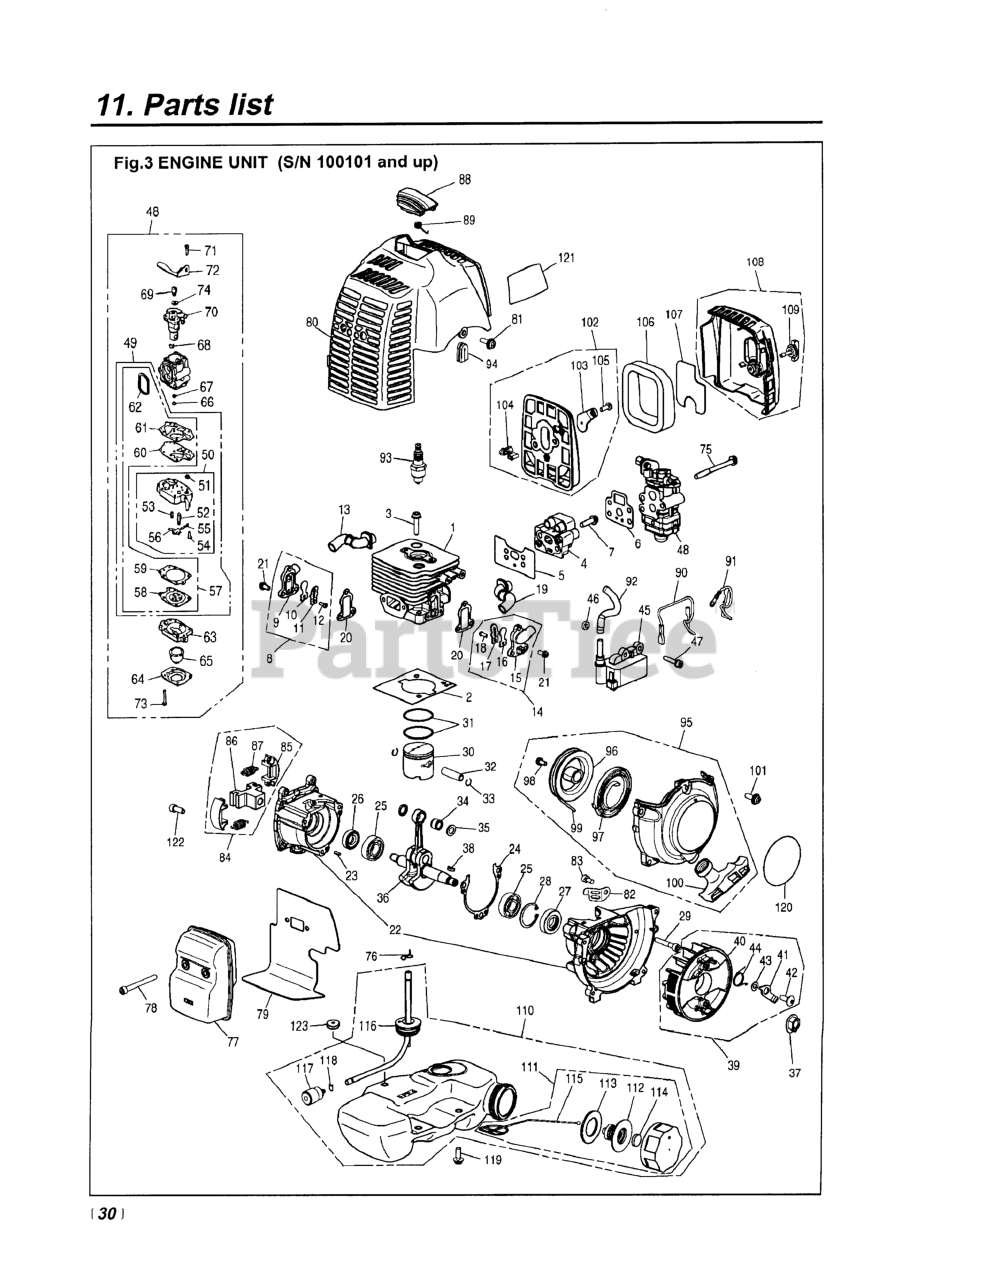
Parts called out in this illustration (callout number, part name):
1	CYLINDER (RPLS -12110)
2	GASKET, BASE
3	BOLT
4	INSULATOR (RPLS. -13160/13161)
5	GASKET INSULATOR
6	GASKET, CARBURETOR
7	BOLT (RPLS 2850-14220)
9	CASE VALVE
10	VALVE, REED
11	STOPPER
12	SCREW, M3 x 8
13	PIPE, AIR
16	VALVE, REED
17	STOPPER
18	SCREW, M3 x 8
19	PIPE, AIR (F)
20	GASKET, VALVE
21	BOLT, TORX
22	CRANKCASE COMPLETE
23	PIN
24	GASKET
25	BEARING
26	SEAL
27	SEAL, OIL (RPLS 1140-21220)
28	RING, SNAP, M28 x 1.2
29	BOLT
30	PISTON
31	RING, PISTON
32	PIN, PISTON
33	RING, SNAP (RPLS 1101-41320)
34	BEARING (RPLS 1140-41330)
35	WASHER
36	CRANKSHAFT-C
38	KEY
39	ROTOR ASSEMBLY
41	PAWL
42	SCREW
43	WASHER
44	SPRING
45	COIL ASSEMBLY
46	SPACER (RPLS -71260)
47	BOLT TORX
48	T1501-81001 (WYA-4-1)
49	KIT, REBUILD (RPLS -06030)
50	PUMP BODY ASSEMBLY
51	SCREEN
52	VALVE, INLET
54	SCREW
55	PIN
56	LEVER
57	KIT, GASKET (REPLACES-06020)
58	DIAPHRAGM
59	GASKET, DIAPHRAGM
60	DIAPHRAGM, PUMP
61	GASKET, PUMP
62	RING
63	BODY, PURGE
64	COVER, PUMP
65	PUMP, PRIMING
66	JET (REPLACES 4810-81250)
67	RING, O
68	RING
69	SWIVEL
70	VALVE ASSY
71	SCREW
73	SCREW
74	WASHER
75	BOLT
76	CLIP
77	MUFFLER
78	BOLT
79	GASKET (RPLS T1501-15210)
80	COVER, ENGINE
81	BOLT
83	BOLT
87	SPRING
89	SPRING
90	CORD (REPLACES T1501-71240)
91	CORD (REPLACES T1512-71250)
92	TUBE
94	GROMMET
95	RECOIL ASSEMBLY
96	REEL
97	SPRING, SPIRAL
98	SCREW (RPLS -75150)
99	ROPE
100	KNOB (RPLS -75420)
101	BOLT
102	BODY ASSEMBLY
103	PLATE, CHOKE
105	SCREW (REPLACES 50030272)
106	ELEMENT
107	SCREEN
108	COVER ASSEMBLY
109	KNOB (RPLS -82220)
111	CAP ASSY (RPLS -85201)
112	HOLDER (REPLACES -85230)
113	PACKING
114	FILTER
115	STOPPER
116	PIPE COMPLETE
117	FILTER (RPLS 1850-85300)
118	CLIP (REPLACES 2841-31280)
120	LABEL, RECOIL
121	LABEL, COVER
122	BOLT (RPLS. T1501-11120)
123	PACKING
